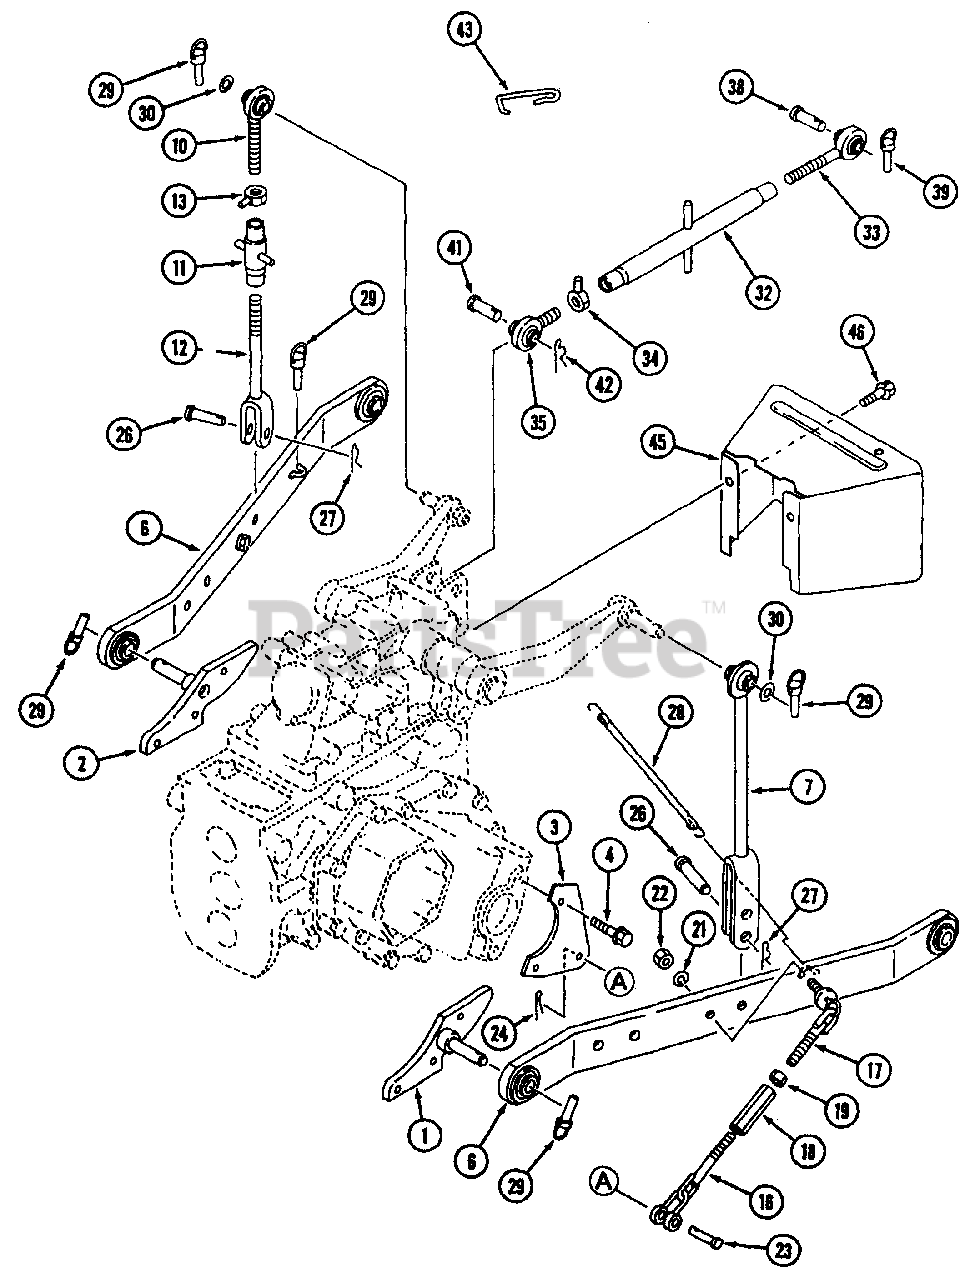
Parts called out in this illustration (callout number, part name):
1	Bracket, L.H.
2	Bracket, R.H.
7	Rod, Lift L.H.
11	Lift Rod, Middle
13	Nut, Lock
26	Pin, Lift Rod
29	Linch Pin
38	Pin, Upper Link
39	Linch Pin
43	Hook, Top Link
45	Cover, PTO
